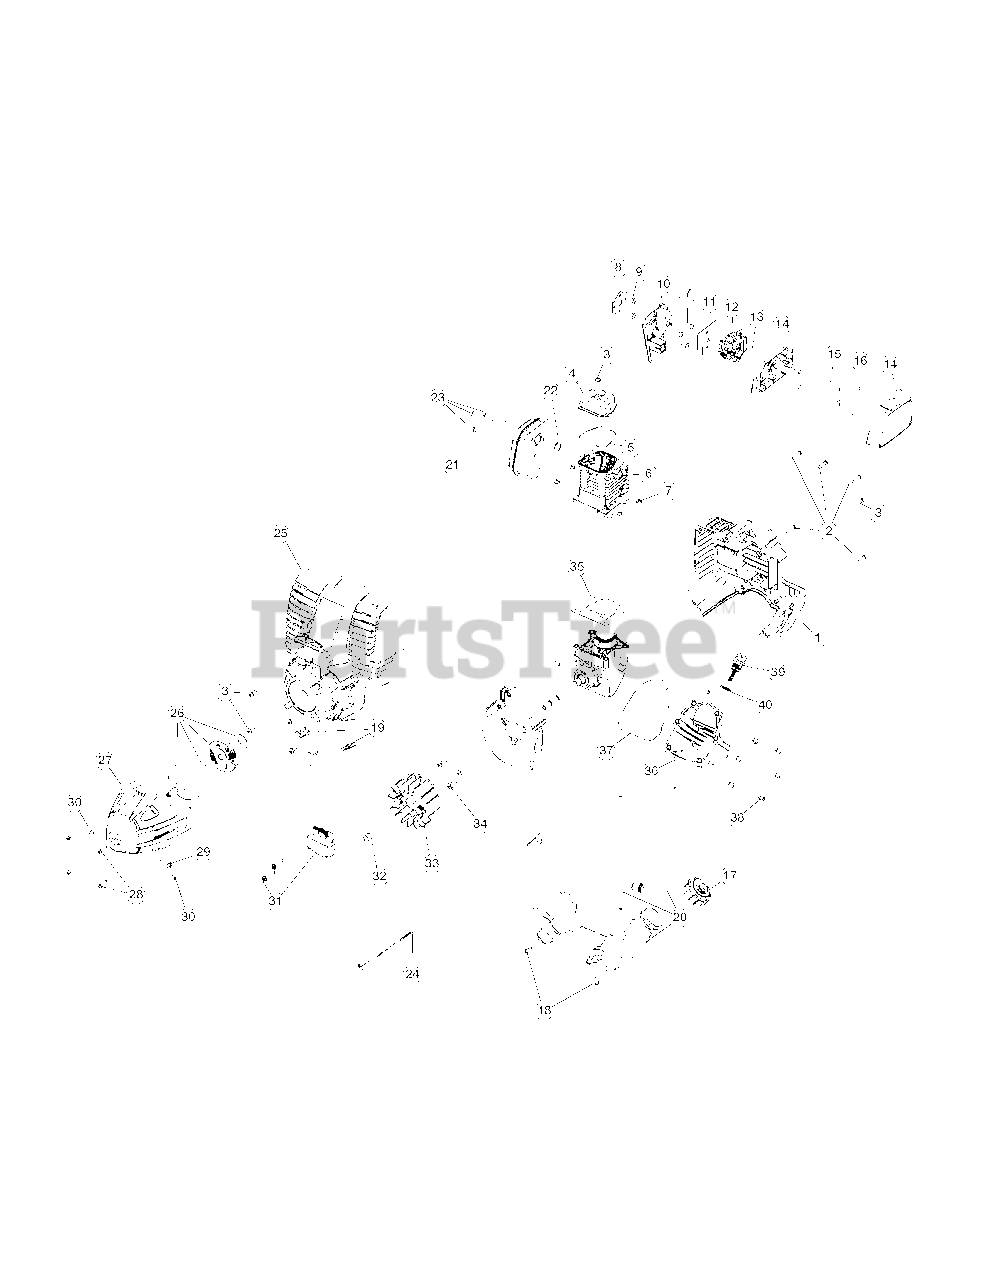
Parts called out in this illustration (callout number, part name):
1	Engine Cover
4	Valve Cover
5	Valve Cover Gasket
6	Cylinder Assembly (Incl. Ref No. 5, 7 & 35)
7	Cylinder Screw
8	Insulator Gasket
10	Insulator (Incl. Ref No. 11)
11	Carburetor Gasket
12	Carburetor w/Primer
13	Carburetor O-Ring
14	Air Filter Cover Assembly (Incl. Ref No. 15 & 16)
15	Air Filter Mounting Screw
16	Air Filter
17	Fuel Cap
19	Clip Nut
20	Fuel Tank Assembly (Incl. Ref No. 17)
21	Muffler Assembly (Incl. Ref No. 22 & 23)
22	Muffler Gasket
23	Muffler Mounting Screw
24	Lead Wire
25	Starter Housing Assembly (Incl. Ref No. 3)
26	Clutch Assembly
27	Clutch Cover Assembly (Incl. Ref No. 28-30)
28	Cover Screw
29	Anti-Rotation Screw
30	Clamping Screw Assembly
31	Module Assembly
32	Spacer
33	Flywheel
34	Shroud Screw
35	Cylinder Gasket
36	Oil Pan (Incl. Ref No. 37 & 38)
37	Oil Pan Gasket
38	Oil Pan Screw
39	Dipstick Assembly (Incl. Ref No. 40)
